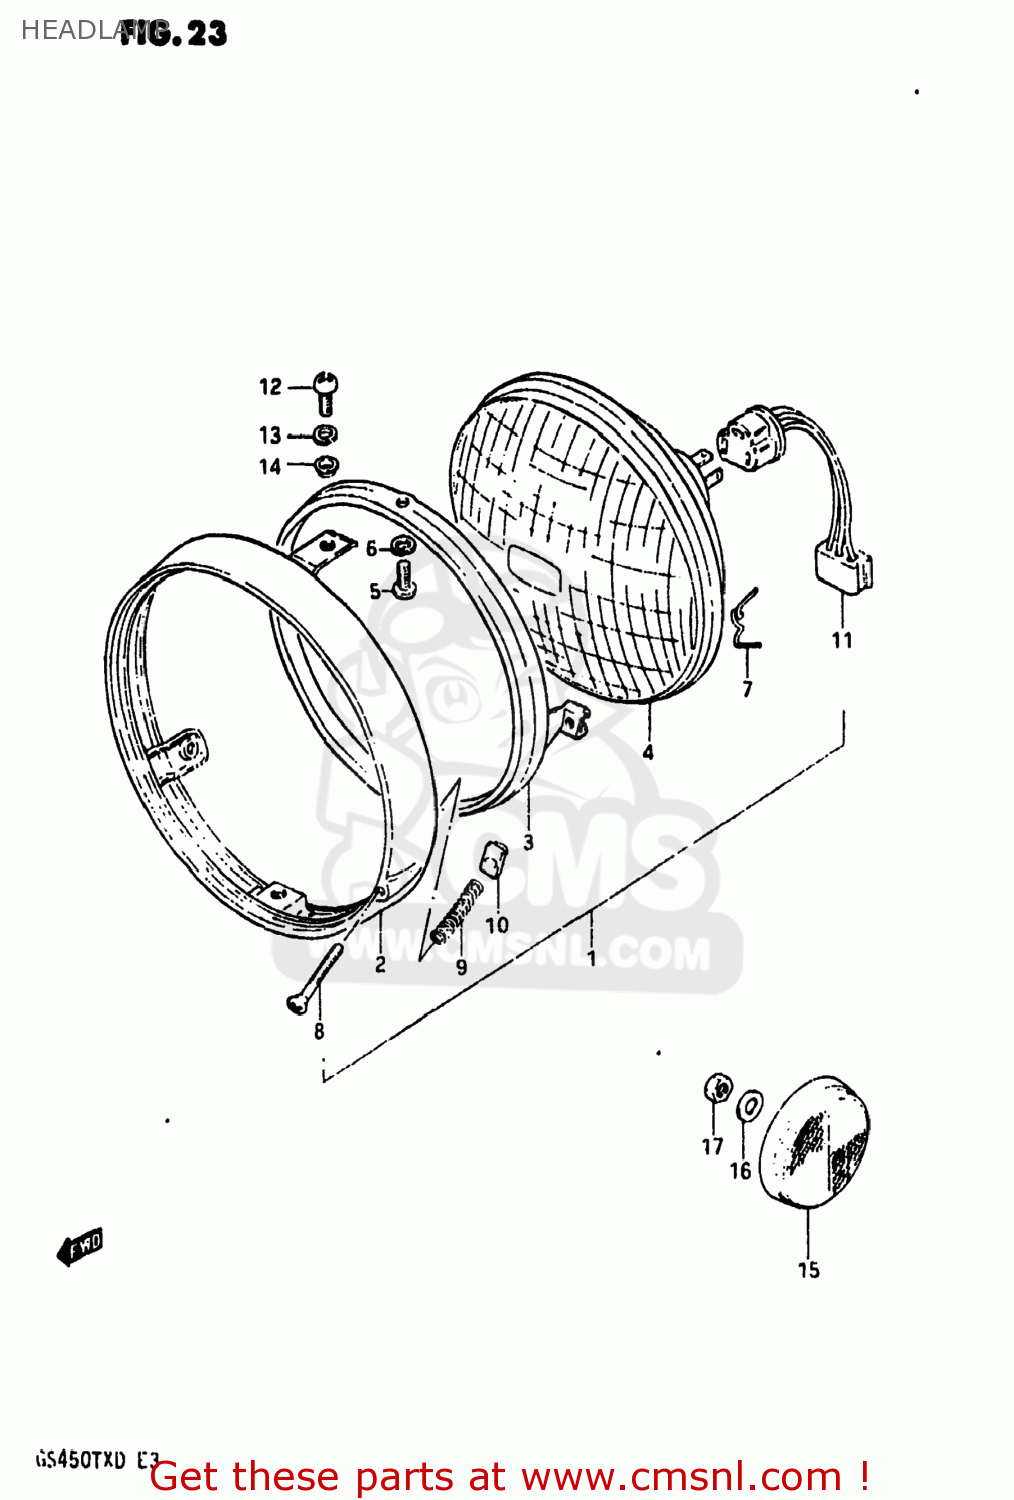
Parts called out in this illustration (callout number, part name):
1	HEADLAMP ASSEMBLY
2	RIM,HEADLAMP
3	RETAINER,HEADLAMP
4	LAMP UNIT
5	SCREW
6	LOCK WASHER
7	SPRING
8	SCREW,HEADLAMP ADJUST
9	SPRING
10	NUT
11	LEAD WIRE,HEADLAMP
12	SCREW
13	WASHER,LOCK
14	WASHER
15	REFLEX REFLECTOR,RR
16	WASHER
17	NUT
